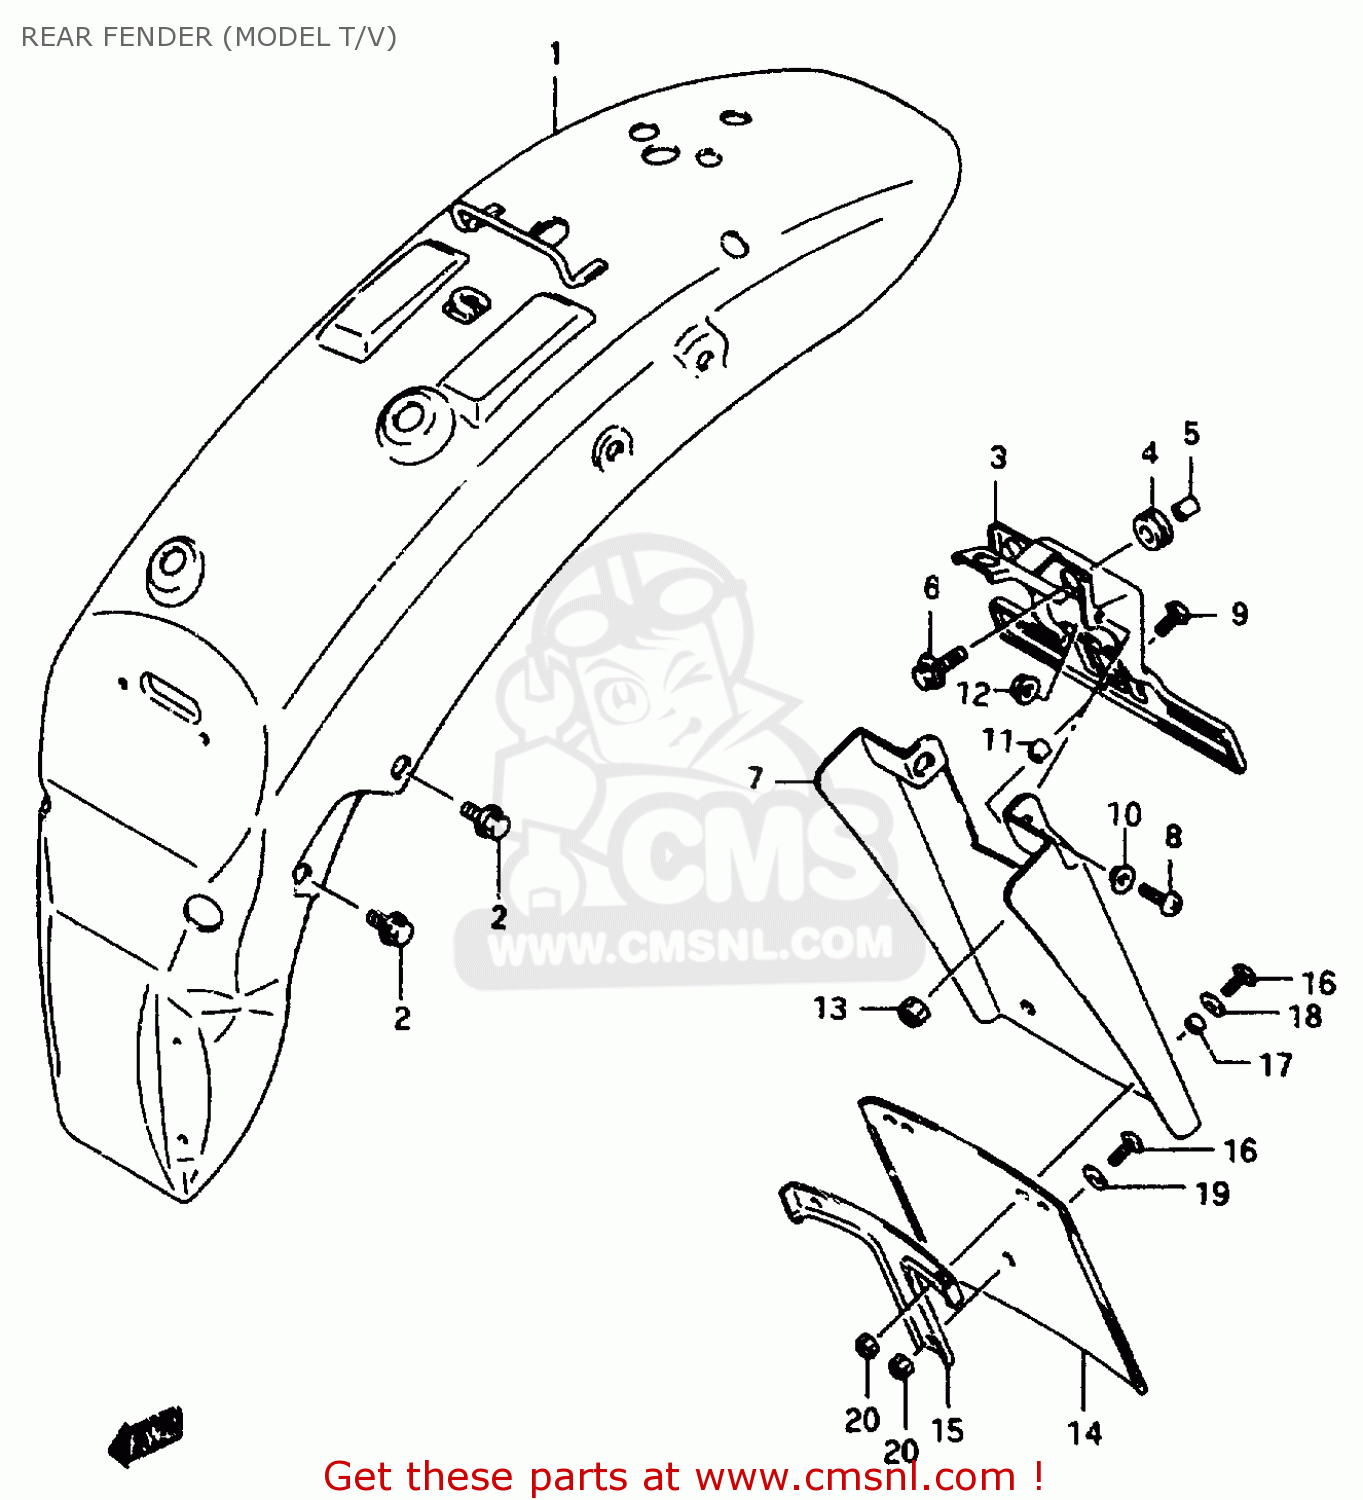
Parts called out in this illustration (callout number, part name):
1	FENDER,RR
2	BOLT
3	BRACKET,LICENSE LAMP
4	CUSHION
5	SPACER
6	BOLT(6X20)
7	EXTENSION,RR FENDER
8	SCREW
9	SCREW 6X16
10	WASHER
11	SPACER(6.2X8.3X6.1)
12	NUT
13	NUT
14	MUD FLAP, REAR FENDER
15	PLATE, MUD FLAP
16	SCREW 5X12
17	SPACER (5.5X8X4)
18	WASHER
19	WASHER(5.5X16X1.2)
20	NUT 8MM
